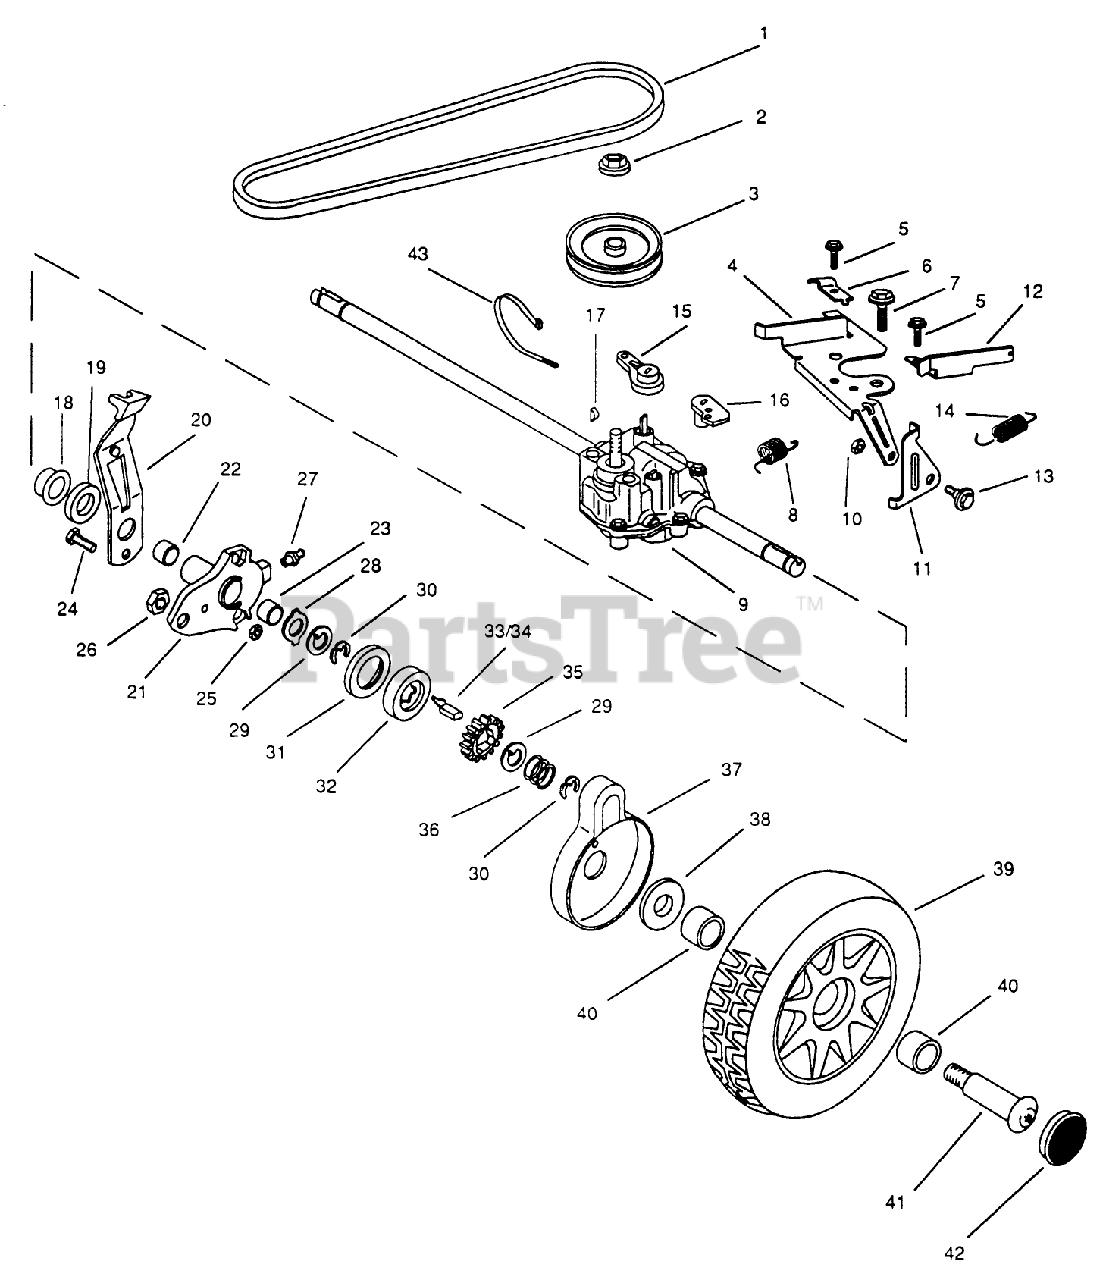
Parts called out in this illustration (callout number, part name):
1	V BELT SM
3	PULLEY TRANS ADAMS
6	CLAMP-CABLE
10	LOCKNUT
16	ARM - CLUTCH
17	KEY GALGER
18	RING ISO
19	SPACER-SHAFT, AXLE
20	KNOB&SPRING AY.
24	SCREW
25	LOCKNUT E
26	NUT-JAM, LOCKING
38	WASHER-STEPPED
40	BUSHING
41	SHOULDER BOLT
42	CAP-HUB
